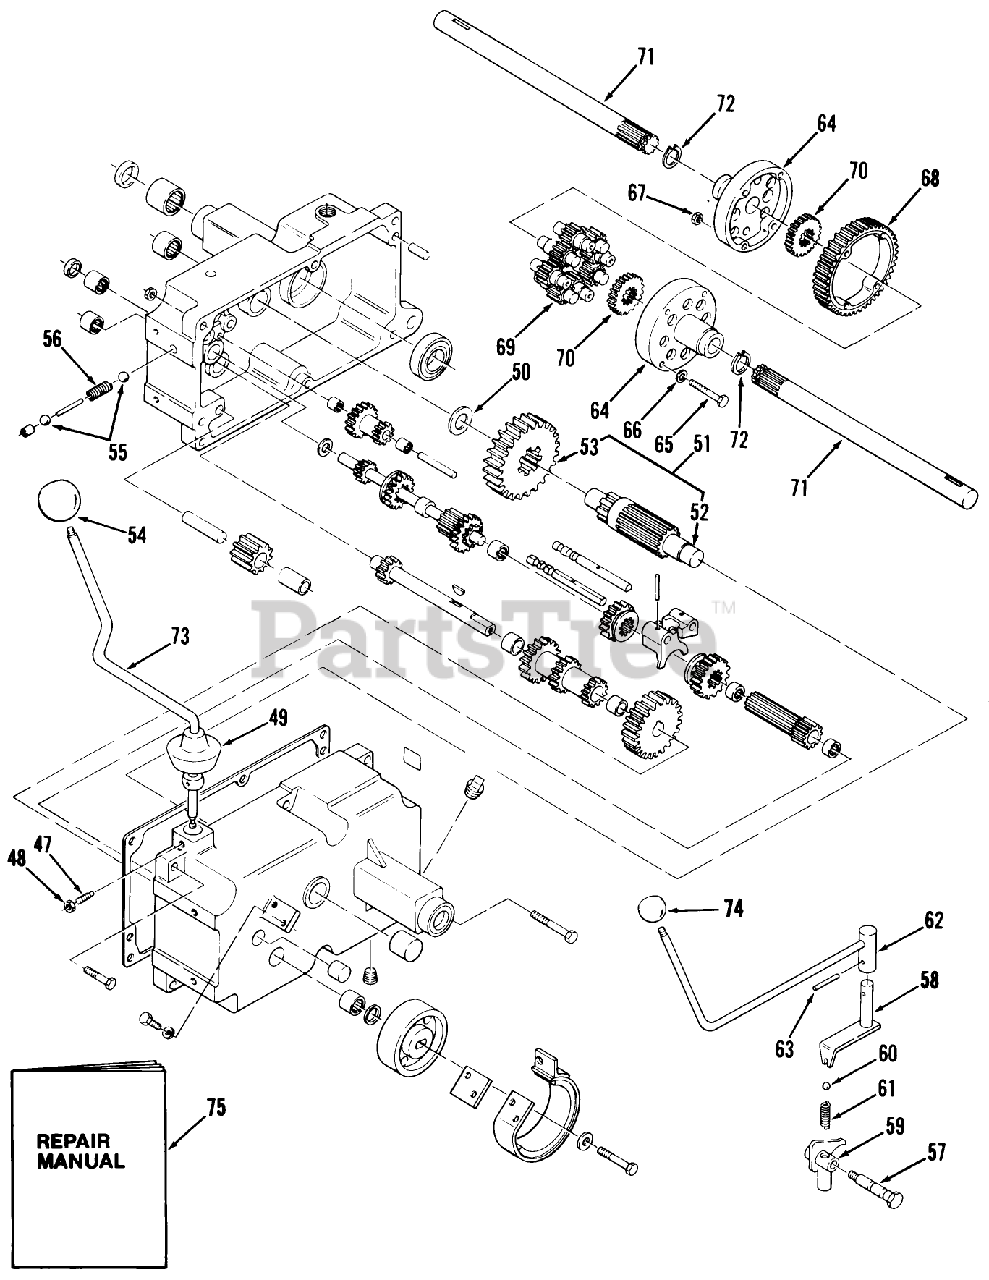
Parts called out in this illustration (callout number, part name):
47	SETSCREW
49	COVER-DUST
50	WASHER-THRUST
51	GEAR ASM
52	PINION SHAFT
55	BALL-DETENT
56	SPRING-SHIFT STOP
57	BOLT-DETENT
58	SHIFT ASM
60	BALL-DETENT
61	SPRING-SHIFT STOP
63	PIN-SPIROL
64	DIFFERENTIAL END CAP
66	WASHER
67	NUT-HEX
68	GEAR-DIFFERENTIAL RING, 43T
69	GEAR-PINION, 11T
70	GEAR-AXLE DIFFERENTIAL
71	AXLE-REAR
72	RING-SNAP
75	MANUAL
